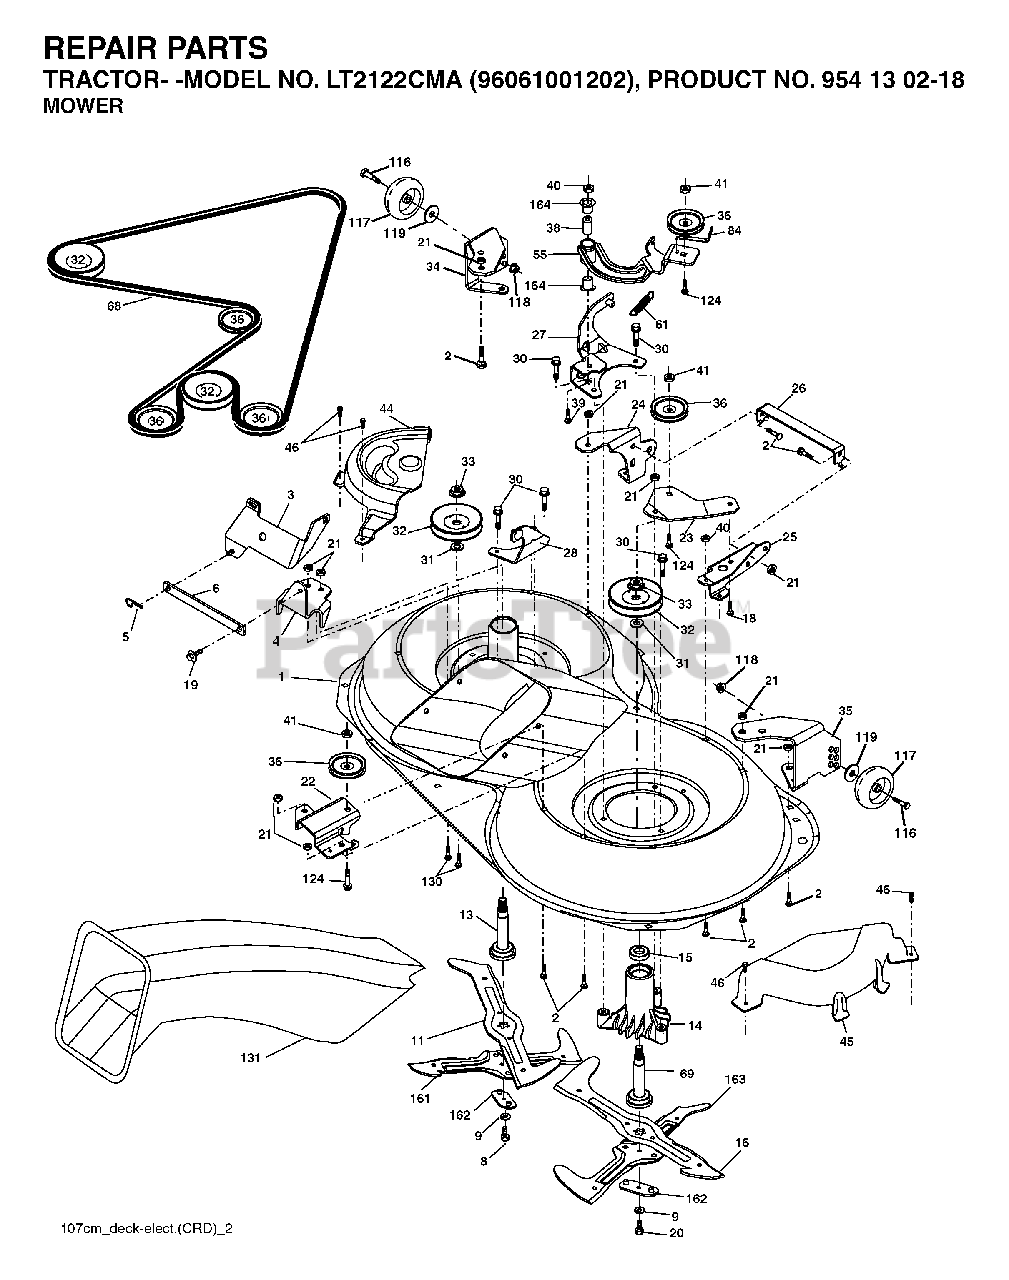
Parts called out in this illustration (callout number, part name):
2	BOLT
3	BRACKET
5	RETAINER-SPRNG RB
6	BAR SWAY
9	LOCKWASHER
11	BLADE.3N1.LH.CRD
13	SHAFT ASM VENT
14	HSG MANDREL
16	BLADE.3N1.RH.CRD
19	BOLT SHD 5/16-18
21	LOCKNUT
22	BRACKET
23	BRACKET
26	BRACE
27	BRACKET
30	SCREW, WASHER HEAD
31	WASHER.SPACER.MANDREL
33	NUT, FLG TOPLOCK 9/16"
36	PULLEY.IDLER.4.25
40	LOCKNUT
41	NUT LOCK FLG 3/8-16 UNC
45	MANDREL COVER
46	SCREW.1/4-20X5/8
55	ARM IDLER
68	HEX-BELT 107 MOWER
69	SHAFT.ASM.W/LWR.BRG.RH.THREAD
84	KEEPER, BELT IDLER
116	SHOULDER BOLT
117	WHEEL GAGE DONUT
118	LOCKNUT
119	WASHER
124	BOLT.3/8-16X1.50
131	CHUTE BAGGER
164	BRNG T
